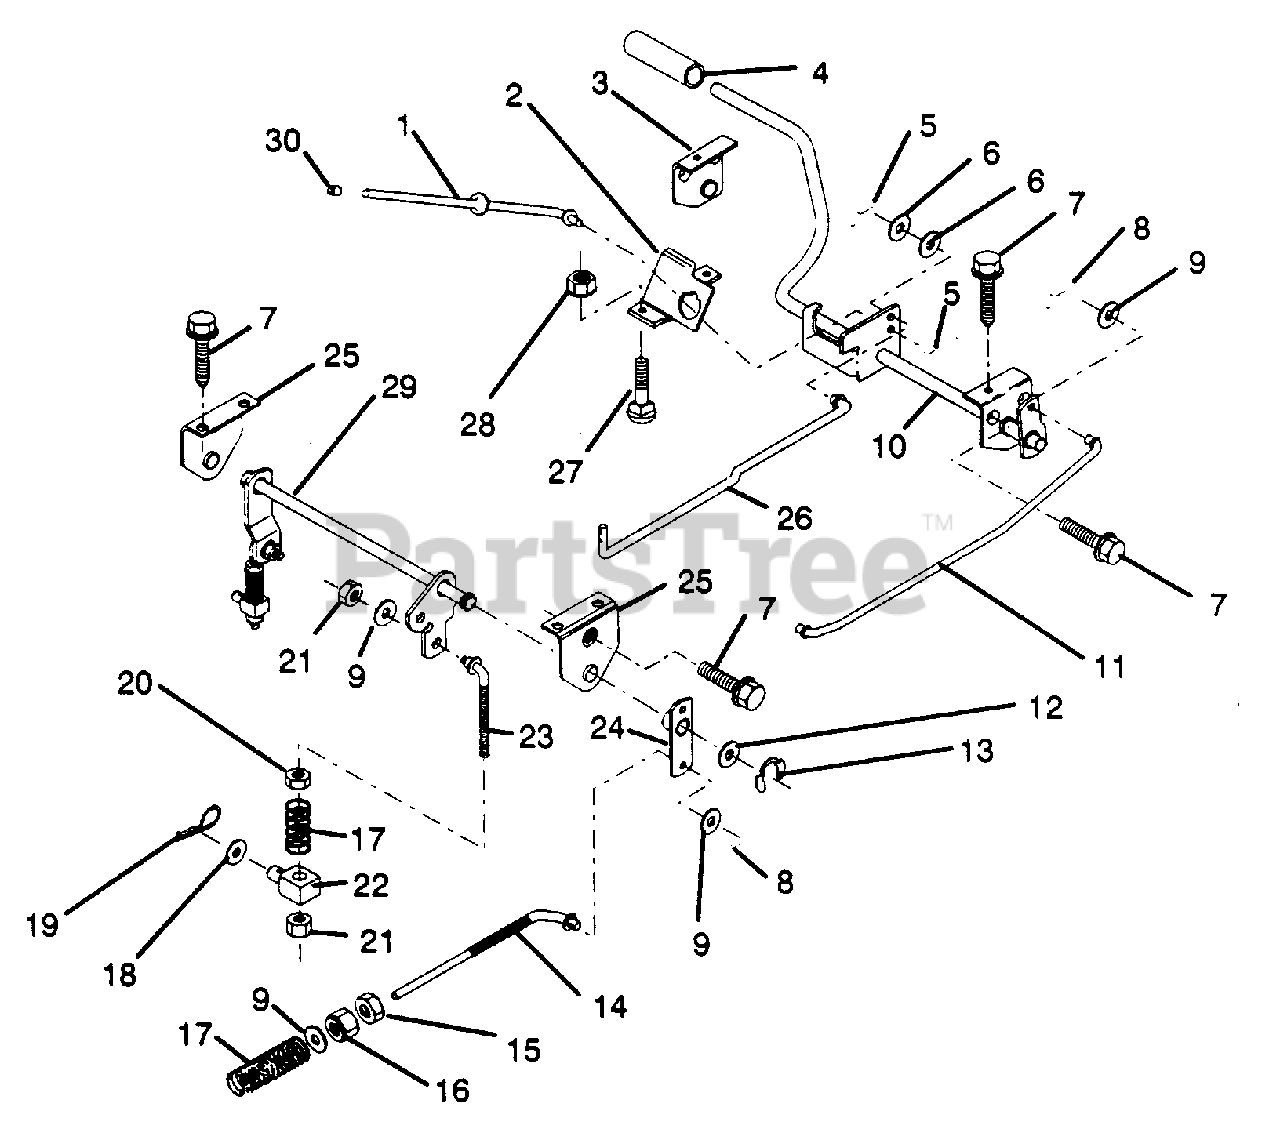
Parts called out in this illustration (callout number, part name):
1	Rod, Parking Brake (AYP part number)
2	Bracket, Parking Brake (AYP part number)
3	Bracket, L.H. Clutch Pedal (AYP part number)
4	Cover, Pedal (AYP part number)
5	Pin, Cotter 3/32 x 3/4 (AYP part number)
6	Washer, 13/32 x 5/8 x 16 Ga. (AYP part number)
7	Screw Hex Thdrol 5/16-18 x 1/2 (AYP part number)
8	Pin, Cotter 3/32 x 3/4 (AYP part number)
9	Washer 13/32 x 13/16 x 16 Ga. (AYP part number)
10	Assembly, Clutch/Brake Pedal (AYP part number)
11	Rod, Front Brake (AYP part number)
12	Washer 25/32 x 1 1/8 x 16 Ga. (AYP part number)
13	Ring, Clip (AYP part number)
14	Rod, Rear Brake (AYP part number)
15	Nut, Hex Jam 3/8-16 UNC (AYP part number)
16	Locknut, Hex w/Washer Insert 3/8-16 UNC (AYP part number)
17	Spring, Brake Rod (AYP part number)
18	Washer 13/32 x 1 1/4 x 12 Ga. (AYP part number)
19	Spring, Retainer (AYP part number)
20	Nut, Centerlock 3/8-16 UNC (AYP part number)
21	Nut, Crownlock 3/8-16 UNC
22	Trunnion, Lift (AYP part number)
23	Link, Threaded (AYP part number)
24	Assembly, Brake Pivot Arm (AYP part number)
25	Bracket, Lift Shaft (AYP part number)
26	Rod, Clutch (AYP part number)
27	Bolt, Carriage 5/16-18 UNC x 3/4 (AYP part number)
28	Nut, Keps 5/16-18 UNC (AYP part number)
29	Assembly, Rear Mower Lift (AYP part number)
30	Cap, Plunger (AYP part number)
